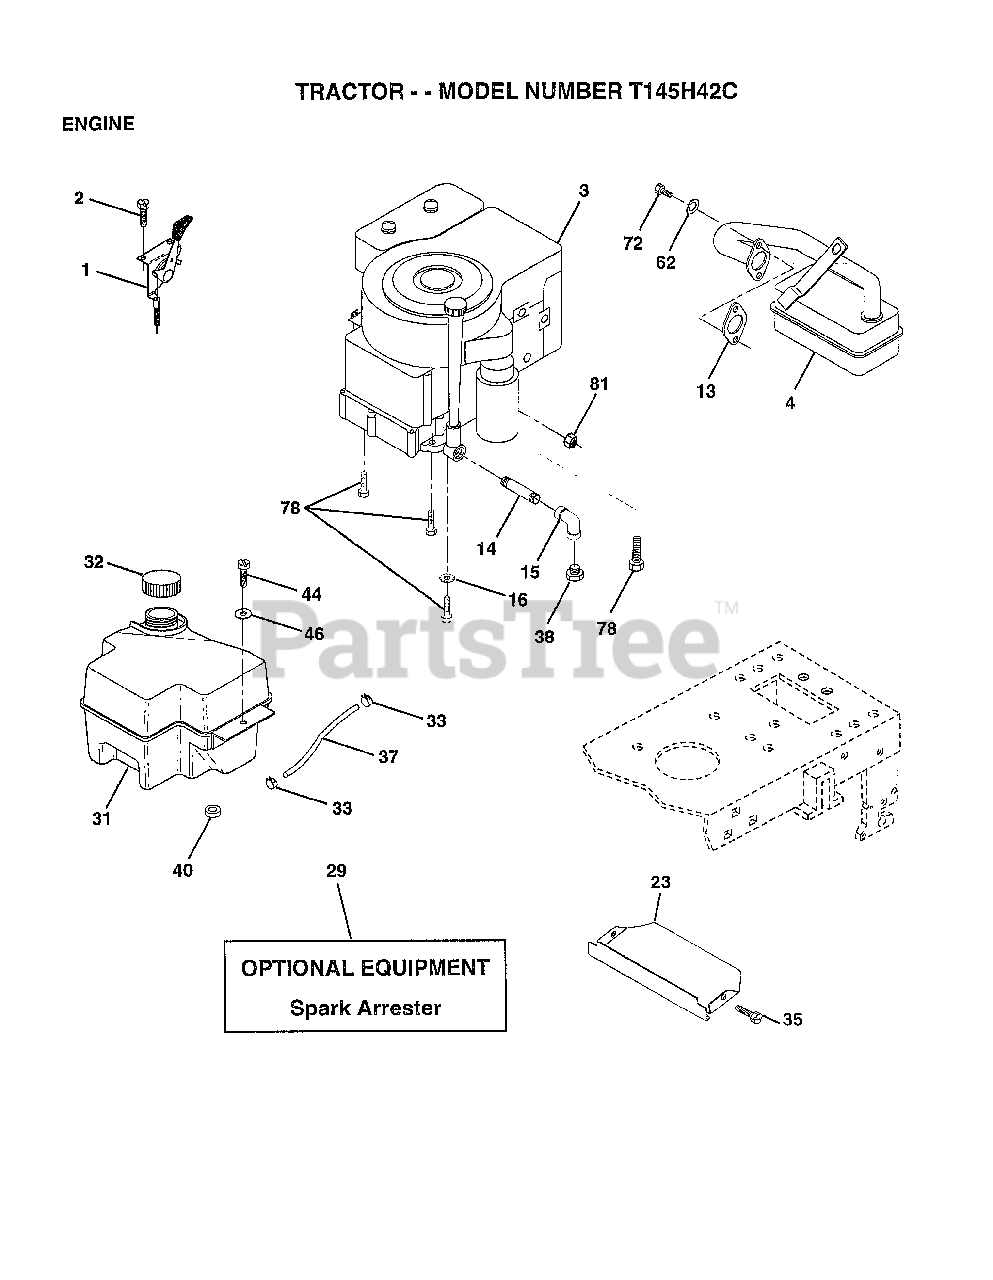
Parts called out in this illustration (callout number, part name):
1	CONTROL THROTTLE
2	SCREW LT
4	MUFFLER
13	GASKET ENG 1 313 LD TIN PLATED
14	PIPE NIPPLE
15	ELBOW
16	LOCKWASHER
23	SHIELD.BRN/DBR.GD
31	TANK.FUEL.FRONT.
32	CAP ASM FUEL
33	HOSE CLAMP
35	SCREW
37	LINE FUEL
44	SCREW HEX CRT
46	WASHER
62	LOCKWASHER
72	SCREW
78	SCREW
81	NUT
